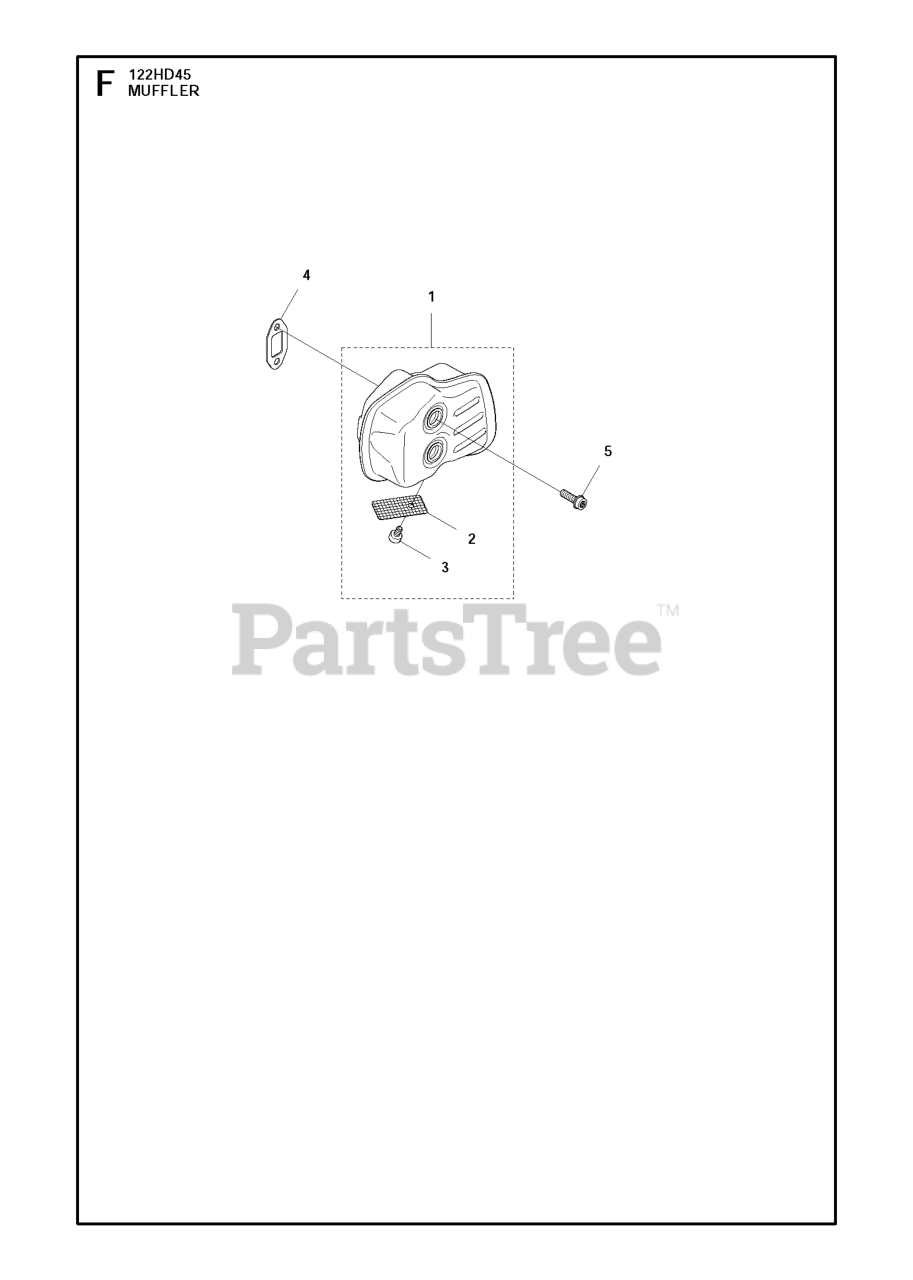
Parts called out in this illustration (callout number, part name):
1	MUFFLER ASSY
2	SPARK ARRESTER
3	SCREW ITXSCM
4	GASKET MUFFLER
